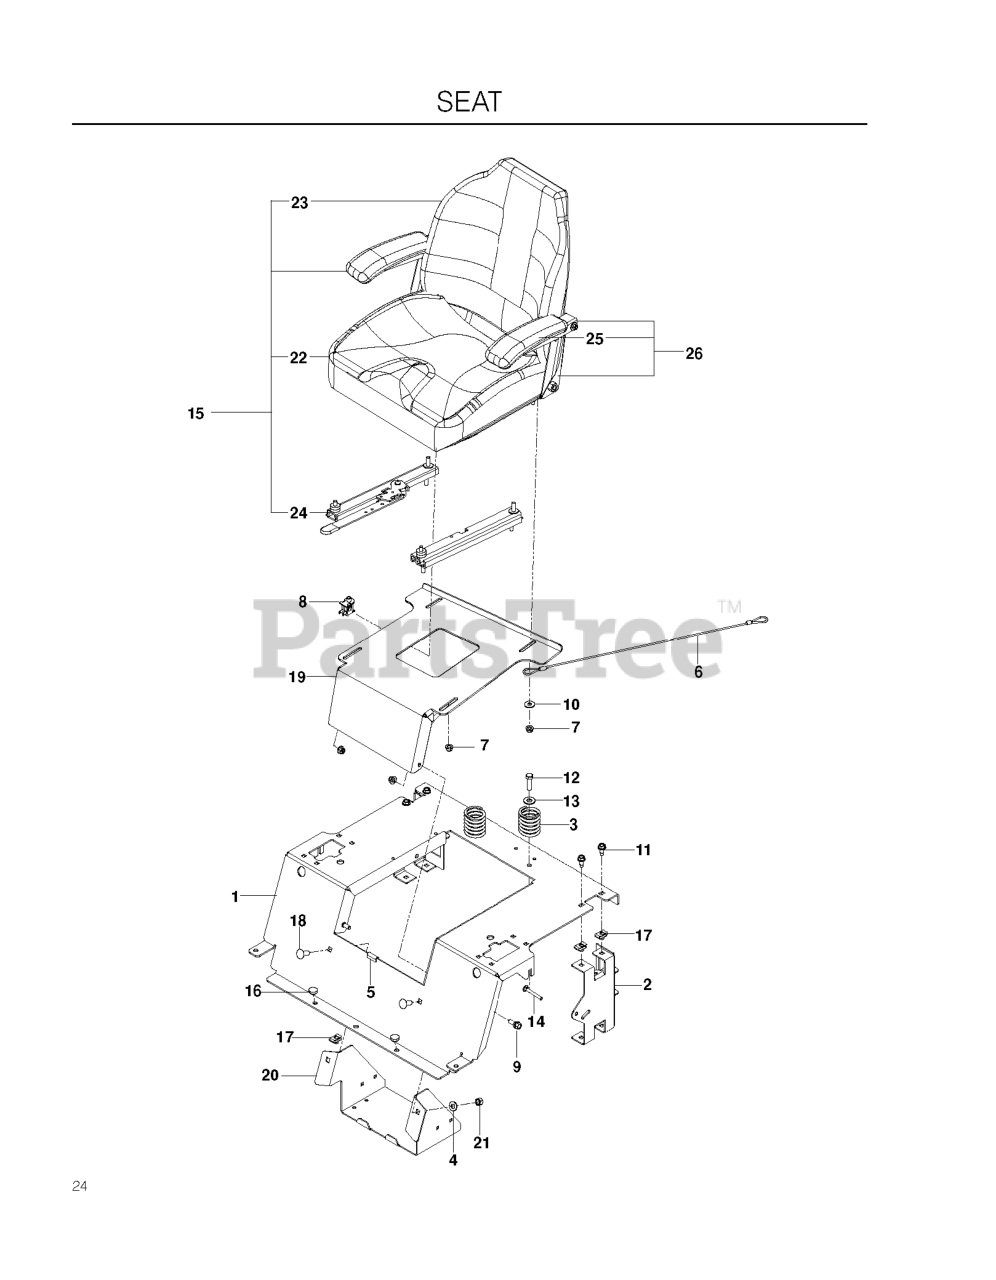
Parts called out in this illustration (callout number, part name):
1	DECK.WLDT.97.CRD.2GWB.
1	SUPPORT, SEAT, FLAT ORANGE
2	SUPPORT, REAR SEAT, BLACK
3	BRACKET.ASM.BAR.SWAY.CHASS
3	SPRING, SEAT
4	WASHER 3/8 SAE FLAT
5	RETAINER-SPRNG RB
6	BAR.SWAY.92.CRD
6	SEAT LANYARD
7	5/16-18 NYLOC FLANGE NUT
8	BOLT.3/8-24X1.25 GR8
8	SEAT SWITCH
9	LOCKWASHER
9	SB 5/16-18 HEX HD GD5, BLK ZN
10	WASHER.BLADE
10	WASHER 5/16 FLAT
11	BLADE.3N1.LH.CRD.97
11	BOLT 5/16-18 X 3/4
12	HCS 3/8C X 1 1/4 GR5
13	SHAFT ASM VENT
13	WASHER 3/8 FLAT
14	HOUSING.MANDREL.VENTED (MACHD)
14	RHSNB 5/16-18 X 2-1/2 GR5 ZD
15	SEAT.907.VINYL.HUSQVARNA
16	BLADE.3N1.RH.CRD.97
16	GROMMET, BUMPER
17	BOLT.3/8-14X1.25
17	U-CLIP 5/16-18 NUT RETAINER
18	RHSNB 3/8C X 1
19	BOLT SHD 5/16-18
19	PAN, SEAT ORG
20	BOLT.3/8-24X1.25GR8. LHTHRD
20	BOX, BATTERY, BLACK
21	NUT 3/8-16 NYLOC
22	BRACKET.SUPT.IDLER.REAR.RH
22	CUSHION ASSY FOR EVC 907
23	BACK ASSY FOR EVC 907
24	4"SINGLE LOCK TRACK SET W/HDWR
25	BLACK SELFSKIN-ARM PAD ONLY
26	LEFT SELFSKINNED 907 ARM W/BRK
27	BRACKET.ASM.SUSP.REAR.RH.
30	SCREW, WASHER HEAD
31	WASHER.SPACER.MANDREL
32	PULLEY MANDREL
33	NUT.FLANGE.LOCK.TOP
36	PULLEY.IDLER.4.25
41	NUT LOCK FLG 3/8-16 UNC
44	COVER MANDREL LEFT
45	COVER MANDREL RIGHT
46	SCREW.1/4-20X5/8
55	ARM.IDLER.92 CRD.2006
56	SPACER.RETAINER.MOWER
61	SPRING
68	BELT.DRIVE.CRD.97.2010
69	SHAFT.ASM.W/LWR.BRG.RH.THREAD
80	PALNUT 1/4
84	KEEPER, BELT IDLER
116	BOLT.SHOULDER.3/8-16X3-5/8.
117	RP WHEEL. GUAGE RALLY
119	WASHER
124	BOLT.3/8-16X1.50
131	CHUTE BAGGER
260	SCREW 3/8-16X1/2
298	SCREW LT
300	BOLT.SHOULDER
306	WASHER 5/16"
311	COVER RIGHT
312	COVER LEFT
